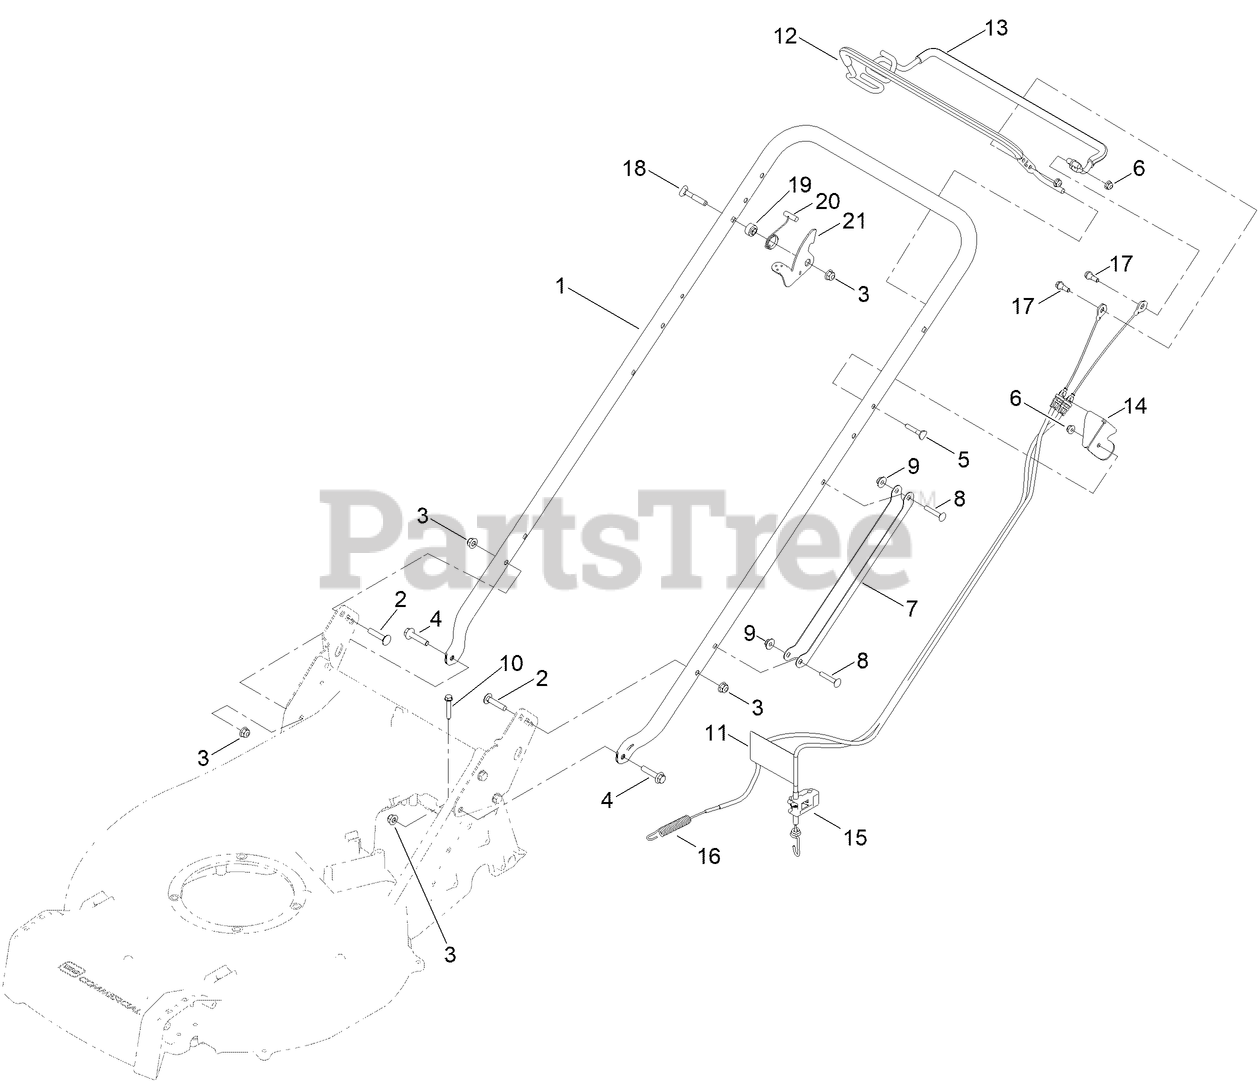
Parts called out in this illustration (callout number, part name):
2	BOLT-CARR
3	NUT-HF, NI
4	SCREW-HHF
5	SCREW-HANDLE
6	NUT-HF
7	GUARD-CABLE, HANDLE
8	SCREW-CARR
9	NUT-HF
10	SCREW-HWH
12	BAIL-BBC, COATED
13	BAIL-TRACTION, COATED
14	BRACKET-CABLE
15	CABLE-TRACTION
16	CABLE-BBC
17	BOLT-SHOULDER
19	BUSHING-STEPPED
20	SPRING-LEVER, BBC
21	LEVER-BBC
